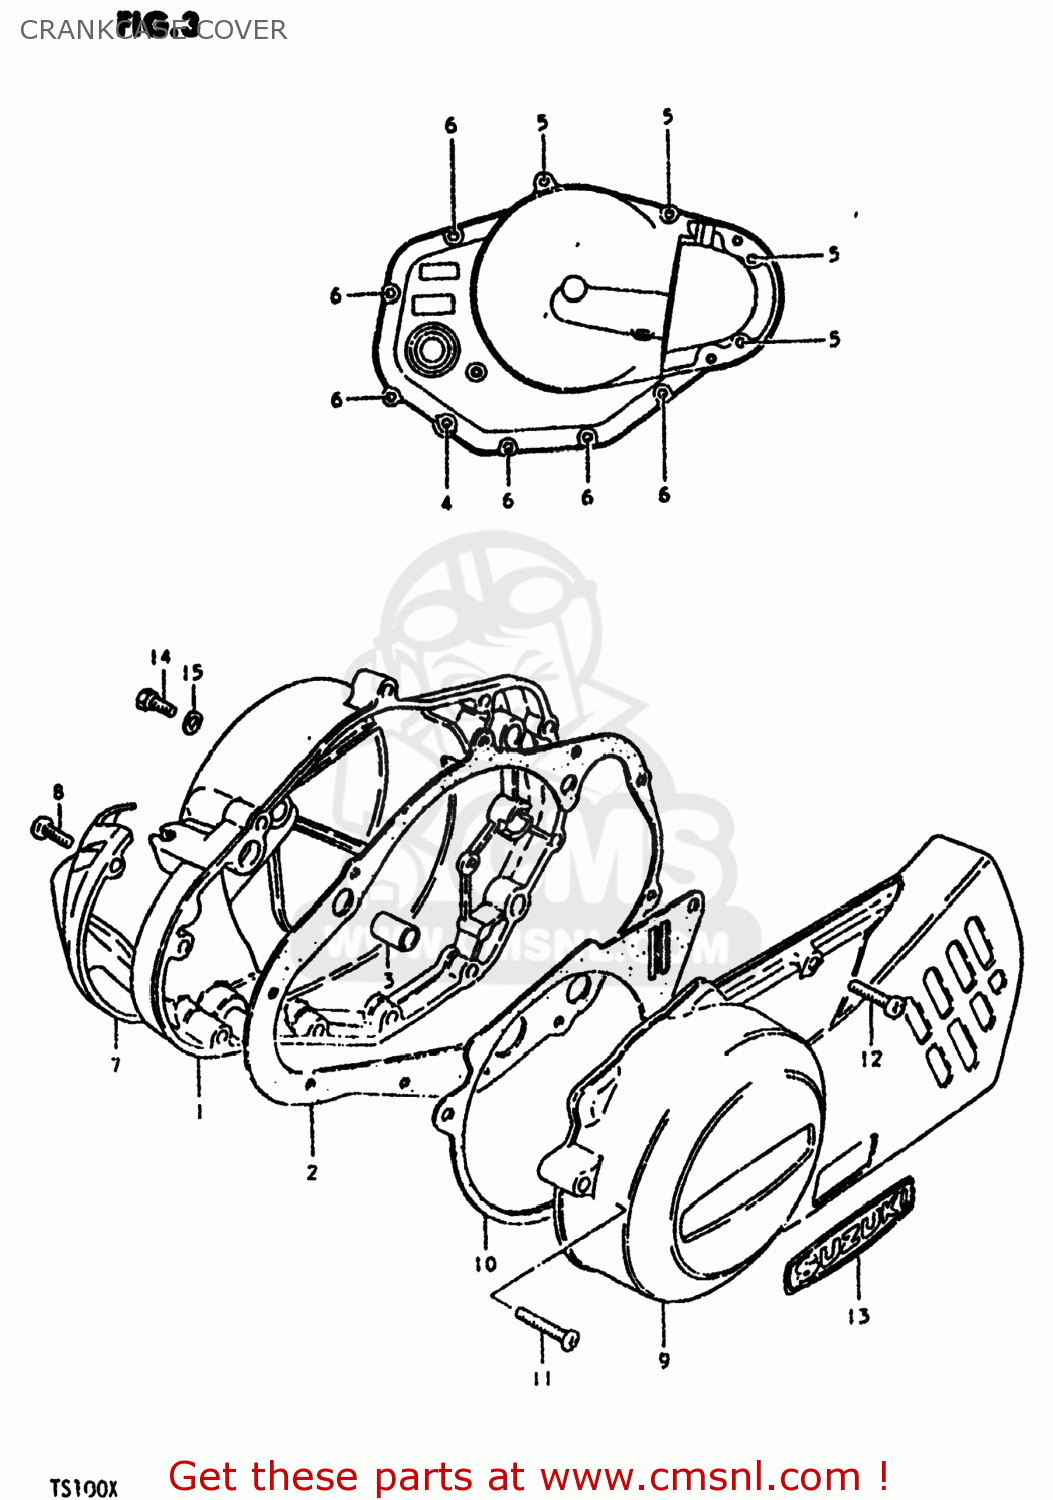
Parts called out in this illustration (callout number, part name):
1	COVER,CLUTCH
2	GASKET,CLUTCH COVER (MCA)
3	PIN
4	SCREW (6X45)
5	SCREW 6X30
6	SCREW
7	COVER,CLUTCH RELEASE ARM
8	SCREW
9	COVER,MAGNETO
10	GASKET,MAGNETO COVER (NAS)
11	SCREW 6X30
12	SCREW
13	EMBLEM,GENERATOR COVER
14	SCREW(6X10)
15	GASKET(6.2X11X1) (NAS)
